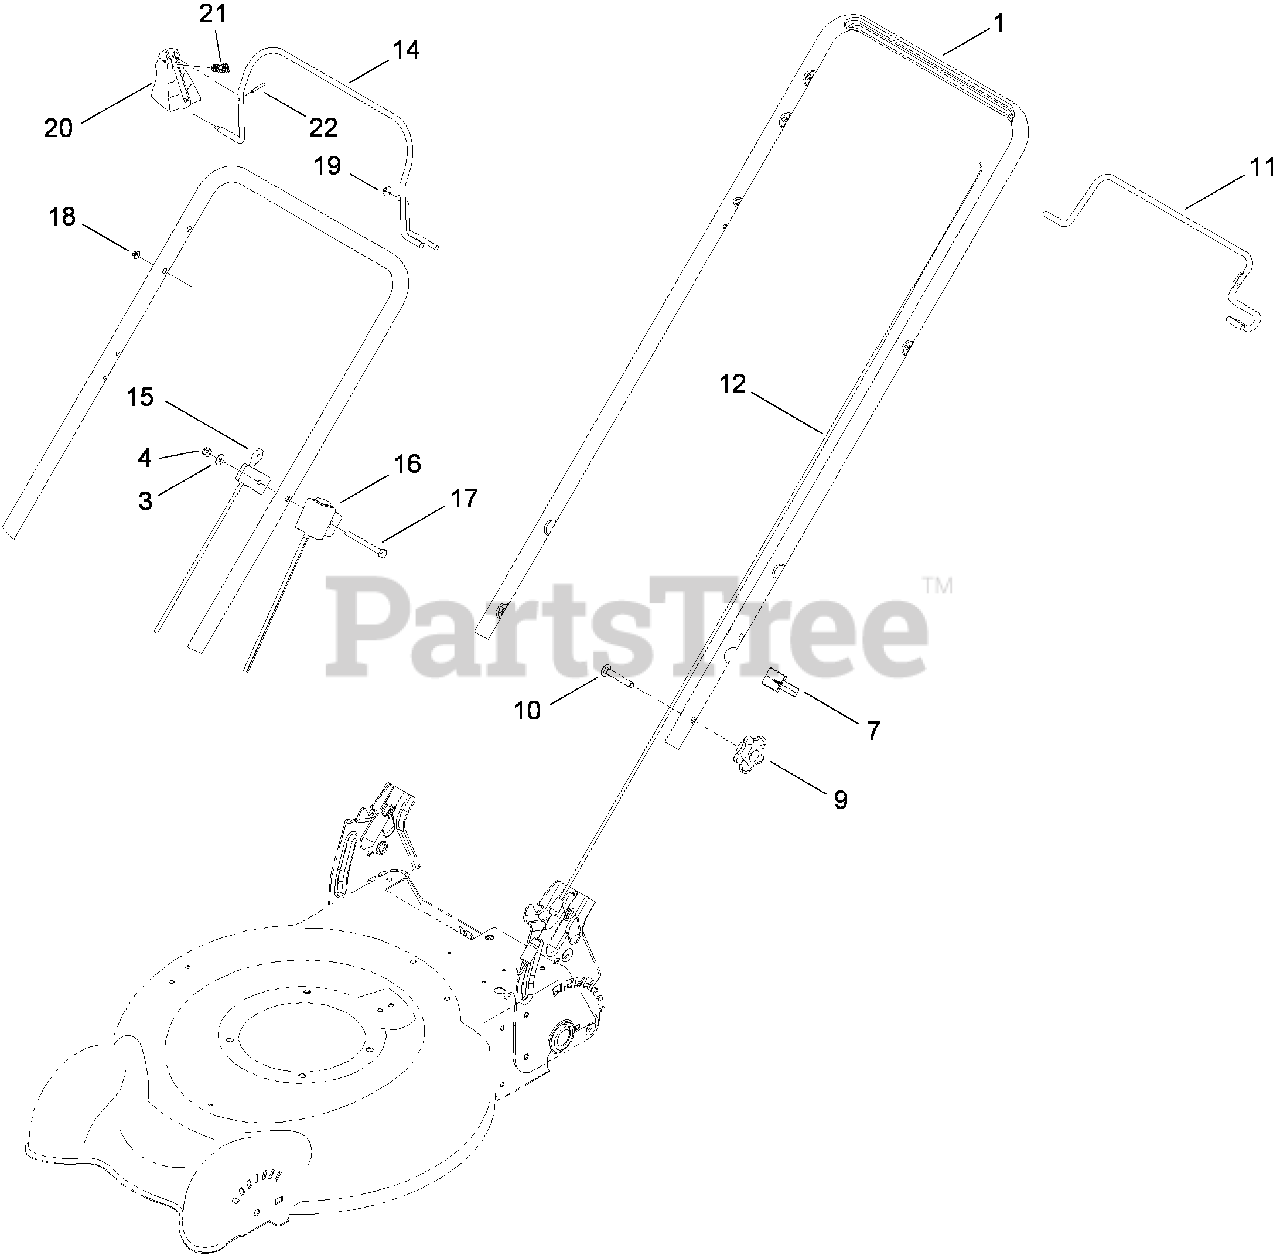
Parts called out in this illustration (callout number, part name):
1	HANDLE-20 INCH
3	WASHER-FLAT
4	NUT-LOCK, NI
7	GUIDE-CABLE
9	KNOB-HANDLE, LOCKING
10	Screw-CARR
11	BAIL-TRACTION, 2-BAIL FLAT
12	CABLE-TRACTION
15	CABLE-BRAKE
16	SWITCH HOUSING ASM
17	SCREW-HH
19	NUT-SPEED
20	STOP-BAIL
21	SPRING-BRAKE
22	PIN-ROLL
